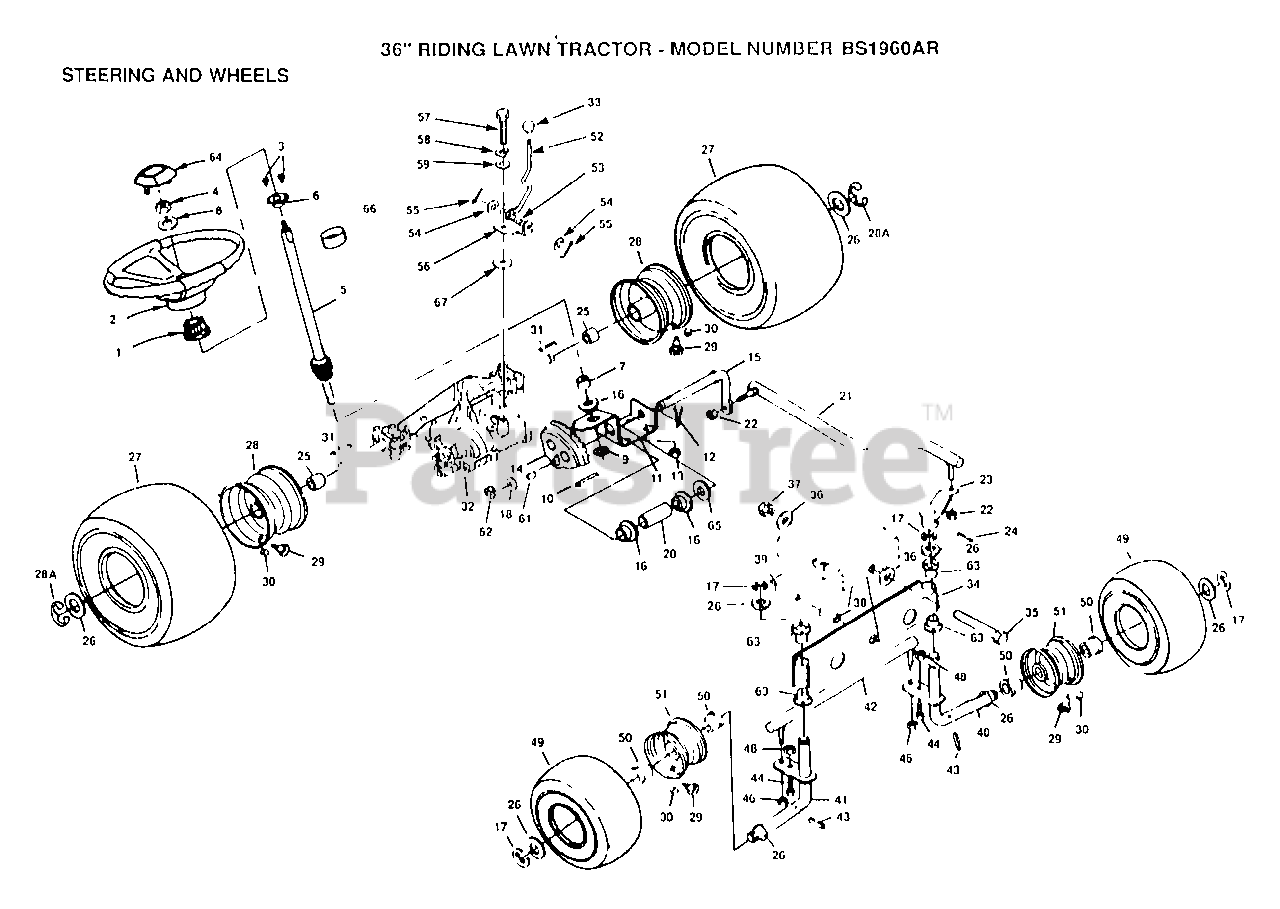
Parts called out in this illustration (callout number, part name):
1	ADAPTER LT
4	NUT
5	STEERING SHFT LT
7	SHAFT SPACER LT
8	WASHER
9	WASHER
11	REAR COVER T
12	BOLT
14	GEAR LT
15	STEERING ROD LT
16	BUSHING
17	RING
18	WASHER
22	GRIPCO NUT
23	STEERING ARM T
25	SPACER LT
26	WASHER
28A	E-RING LT
29	VALVE STEM LT
30	VALVE CAP
32	No Desciption for Part
33	KNOB T (1/2-HOLE)
36	WASHER
37	NUT LTV
38	ROCKER PIVOT LT
39	PIVOT SPACER LT
40	KINGPIN ASSY LH
46	NUT.LOCK.5/16-24
50	"LT, BEARING"
51	RIM ASSY LT
53	SPRING LT
54	WASHER
55	PIN COTTER 1/8
56	SHIFT PLATE LT
58	LOCKWASHER
59	WASHER LT
61	KEY WOODRUFF #9
62	KLIP RING
63	COL. SRTG. BEAR.
64	INSERT-WHEEL LT
65	WASHER LT
